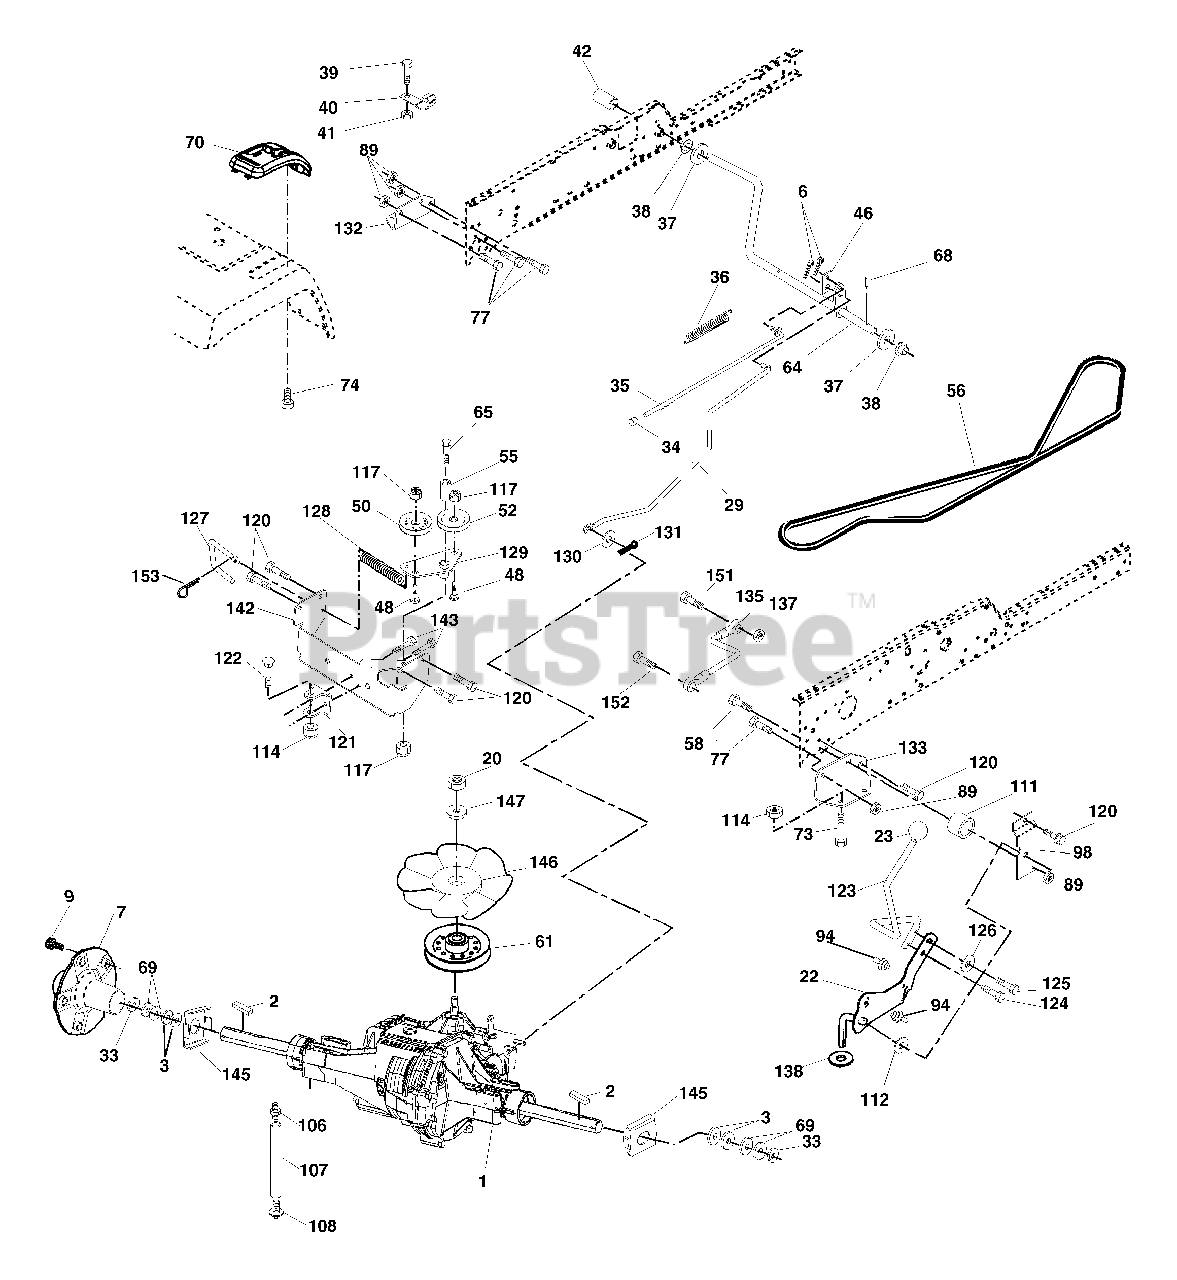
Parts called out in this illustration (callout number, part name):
2	Key Sq. 1/4 x 1/4 x 2.5
3	Washer Thrust
6	Pin, Cotter
7	Wheel, Hub Assembly
22	Lever Asm Shift
29	Brake, Rod
34	Cap, Parking Brake
35	Rod, Parking Brake
36	Spring, Drive Ground
37	Washer 25/32 x 1-1/4 x 16 Ga.
39	Screw, Fin. #10-24 x 1
40	Actuator, Interlock VGT
41	Nut Centerlock 10-24 unc
42	Cover, Pedal
46	Retainer, Spring
48	Bolt Rdhd 3/8-16 x 1.3/4 Gr. 5
50	Pulley, Idler, Flat
52	Pulley, Idler, Grooved
55	Bearing, Idler
58	Bolt Fin Hex 7/16-14 x 1-1/2
61	Pulley, Transaxle
64	Shaft, Brake Pedal
65	Bolt, Shoulder
70	Console Automatic YT/GT
73	Bolt Hex Flghd 5/16-18 x 3 Gr. 5
74	Screw Hex Wsh. Hi-Lo 1/4-1/2
77	Bolt Fin Hex 7/16-14 x 1
89	Nut Crownlock 7/16-14 unc
94	Fastener Christmas Tree
98	Bracket Shift
106	O-Ring Asm Hydro Gear
107	Line Fuel Hydro 15" VGT
108	Cap Asm Vent Hydro Gear
111	Spacer Shift Lever VGTH
112	Washer Nylon High Temp
114	Nut Lock Hex W/Ins 5/16-18 unc
117	Nut, Lock Flg. 3/8-16
120	Screw 3/8-16 x .75
121	Bracket Strap Torque
122	Bolt RDHDSQ 5/16-18 unc x 2-1/2
124	Bolt Shoulder 5/16-18 x .561
125	Screw 5/16-18 x 5/8
126	Washer SRRTD 5/16 ID x 1.0 x .125
127	Link Control Clutch
128	Spring Drive GRND
129	Bracket Asm Idler Tensioning
130	Washer 13/32 x 5/8 x 16 Ga.
131	Pin Cotter 3/32 x 3/4
132	Bracket Mtg Hydro 3500 LH VGT
133	Bracket Mtg Hydro 3500 RH VGT
135	Link Asm Control Hydro 3500
137	Nut Lock 5/16-18 NC Thd.
138	Washer Thrust 5/8 x 1.10 x 1/32
142	Strap Torque HG-3500
143	Screw Thdrol 5/16-18 x 3/4
145	Washer Axle Flange HG-3000
146	Fan 7" Hydro
151	Bolt Hex 5/16-18 x 7/8
152	Bolt Hex 5/16 x 1 W/Patch
153	Spring, Retainer
